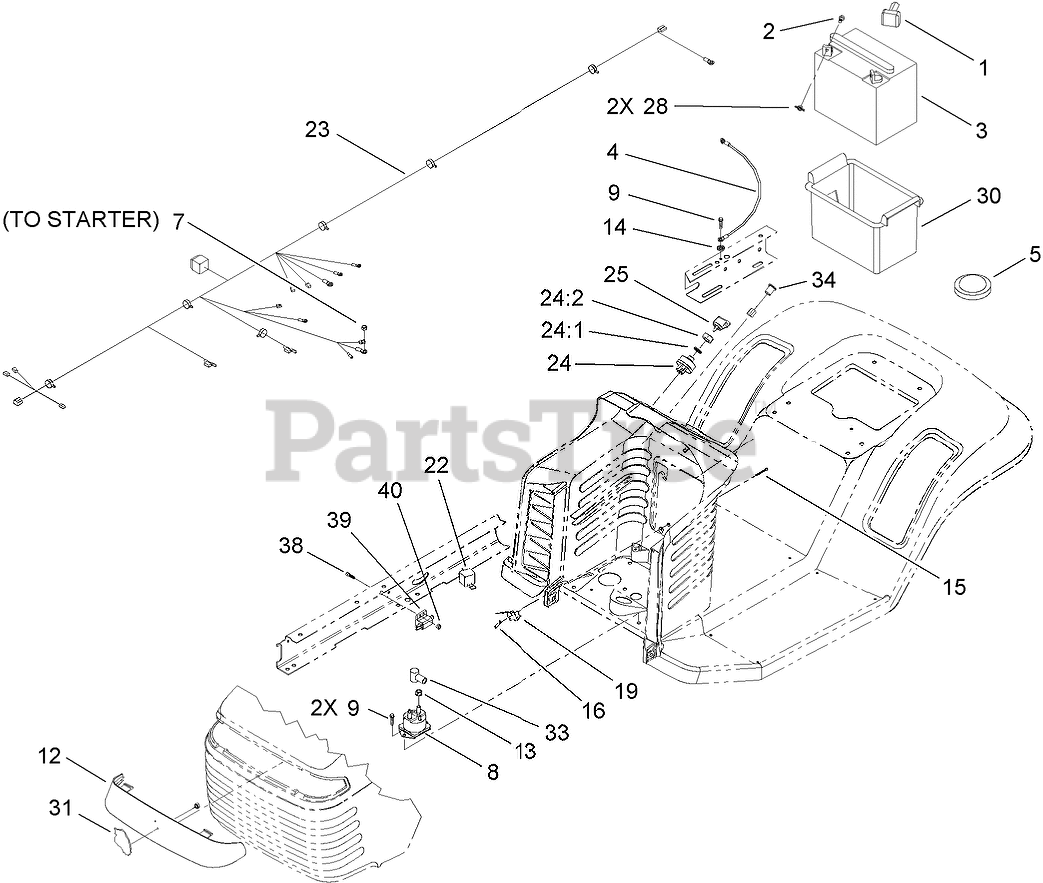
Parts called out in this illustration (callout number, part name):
1	BOOT-TERMINAL
2	SCREW-HH
3	BATTERY-155 CCA
4	WIRE ASM
5	SWITCH-SEAT
7	NUT-KEPS
8	SOLENOID-STARTER
9	SCREW-HWH
12	LENS-HEADLIGHT
13	NUT-KEPS
14	WASHER-LOCK/EXT
15	SCREW-HH
16	NUT-SPEED
19	SWITCH-MICRO
22	RELAY
23	HARNESS-WIRE
24	Key Switch ASM
24:1	WASHER-TOOTH, INTERNAL
24:2	NUT-HH
25	KEY-IGNITION
28	NUT-WING
30	BOX-BATTERY
31	EMBLEM
33	BOOT-INSULATOR, TERMINAL
34	LIGHT-INDICATOR
38	SCREW-HSH
39	SWITCH-POLE, SINGLE
40	NUT-LOCK, NI
